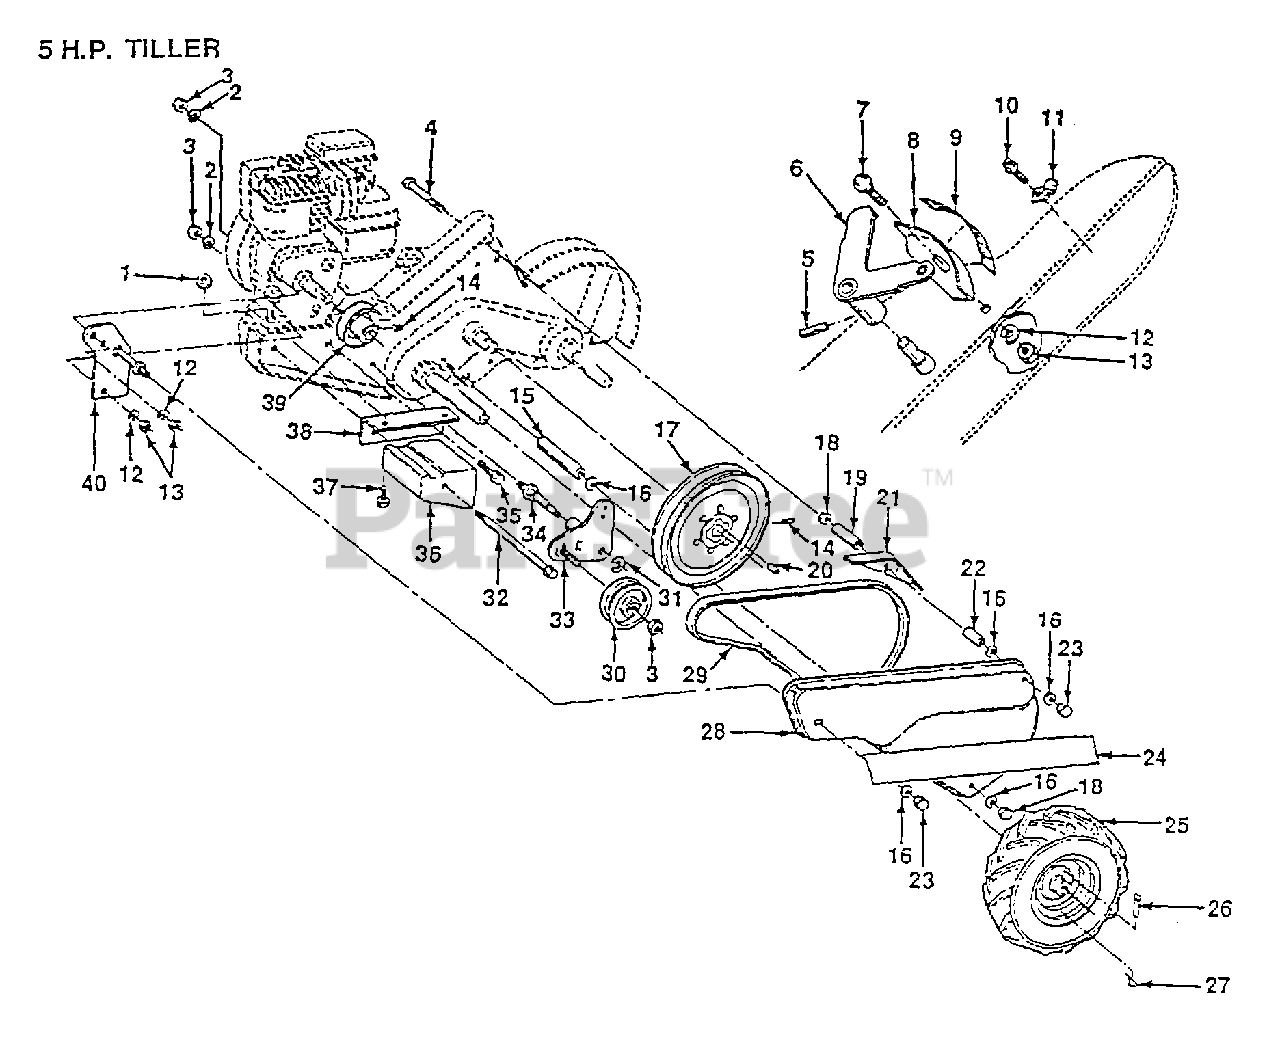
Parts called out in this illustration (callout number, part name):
2	LOCKWASHER
3	NUT.HEX.3/8-16UNC
4	BOLT-HEX TI
6	LEVER ASM CRT
7	BOLT
8	PANEL TI
11	CONDIUT CLIP T
12	LOCKWASHER
14	SET SCREW
15	SPACER
16	WASHER
17	"SHEAVE 10"" CRT"
18	NUT.HEX.5/16-18
19	SPACER CRT
20	KEY T
21	GUARD CRT
22	SPACER CRT
23	NUT TI
24	DECAL, BELT GUARD
25	TIRE.CHV.13X5.0-6
25	RIM
27	RETAINER M
30	PULLEY-IDLER TI
31	KLIP RING
32	BOLT CRT
34	SHIFT ARM CRT
35	BOLT
36	COUNTERWEIGHT CRT
37	BOLT.HEX.5/16-1.5
38	BRACKET LH CRT
40	BRACKET ASSY CRT
